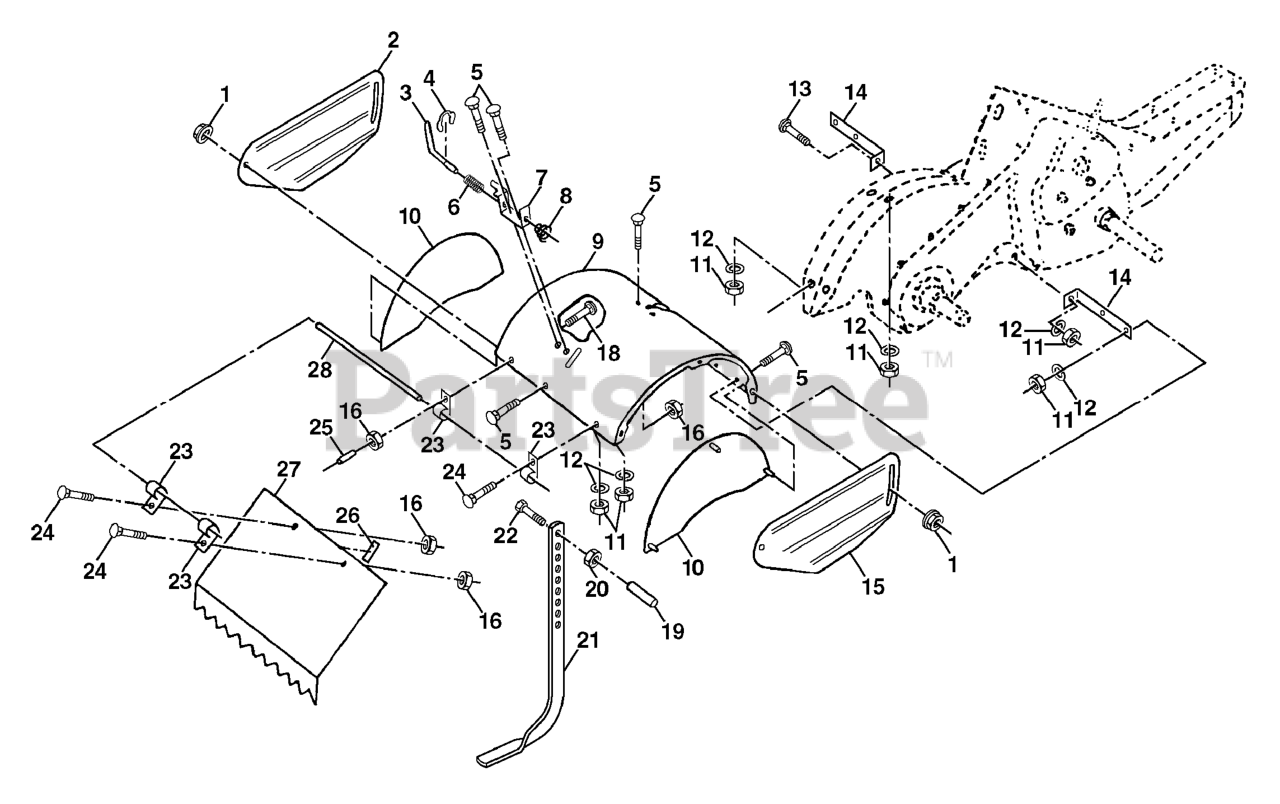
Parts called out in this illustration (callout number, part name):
1	NUT
2	SHIELD SIDE OUTER LH
3	STAKE PIN TI
4	KLIP RING TI
5	RP BOLT 5/16-18 X3/4 ZN/YEL GR
7	BRACKET.LATCH.STAKE.3.20.BLACK
8	SPRING CRT
9	SHIELD
10	BOLT
11	NUT
12	WASHER.LOCK.HVY.HLCL.SPR.5/16
13	BOLT.CARRIAGE.5/16-18
14	BRACKET.TINE.SHIELD.TILLER.BLA
15	SHIELD SIDE OUTER RH
16	NUT
17	LOCKWASHER
20	NUT.HEX.3/8-16UNC
21	STAKE.DEPTH.16.CRT.BLACK
22	BOLT.375-16
24	BOLT
25	VINYL CAP TI
26	PAD IDLER TI
27	SHIELD LEVELING
28	PIN.HINGE.TILLER
29	SIDE SHIELD
30	LOCKNUT-FLANGE 5/16-18
